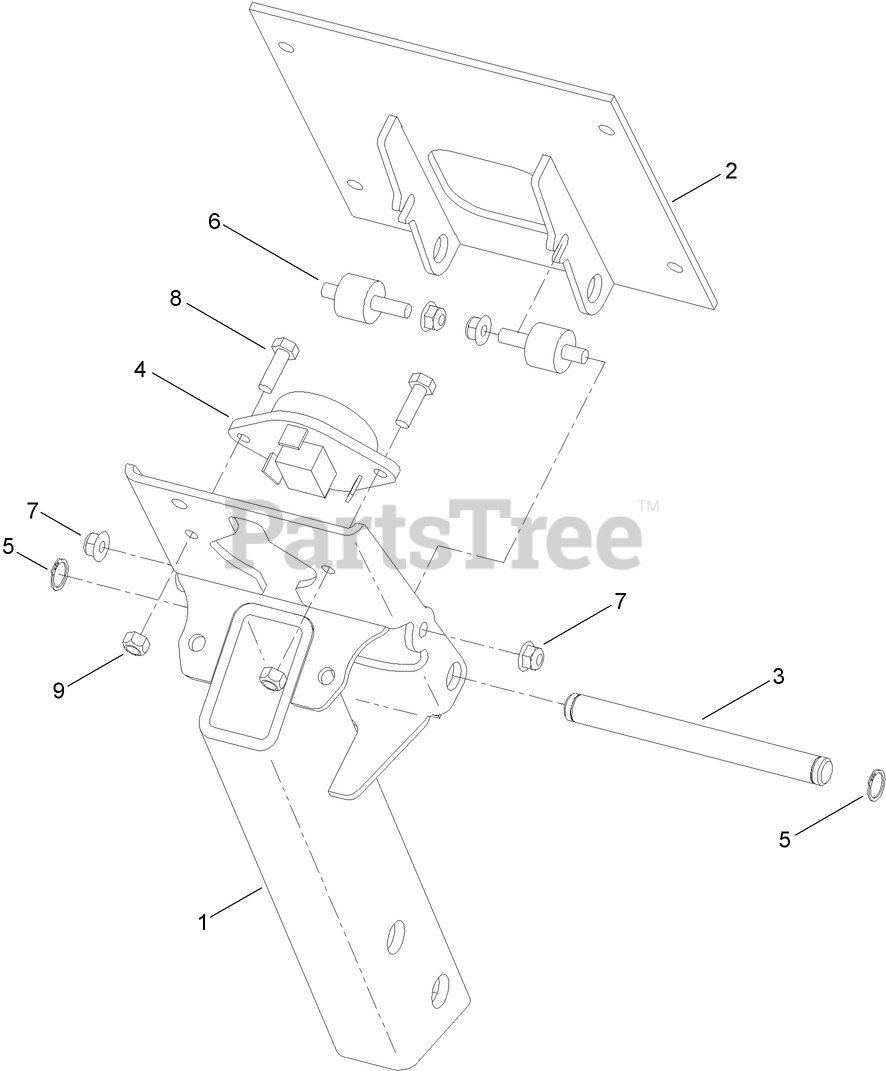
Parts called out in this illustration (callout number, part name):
1	POST-SEAT
2	PAN-SEAT
3	PIN-PIVOT
4	SWITCH-OPS
5	RING-SNAP, EXTERNAL
6	MOUNT-RADIATOR
7	NUT-HF, NI
8	SCREW-HH
9	NUT-LOCK, NI
